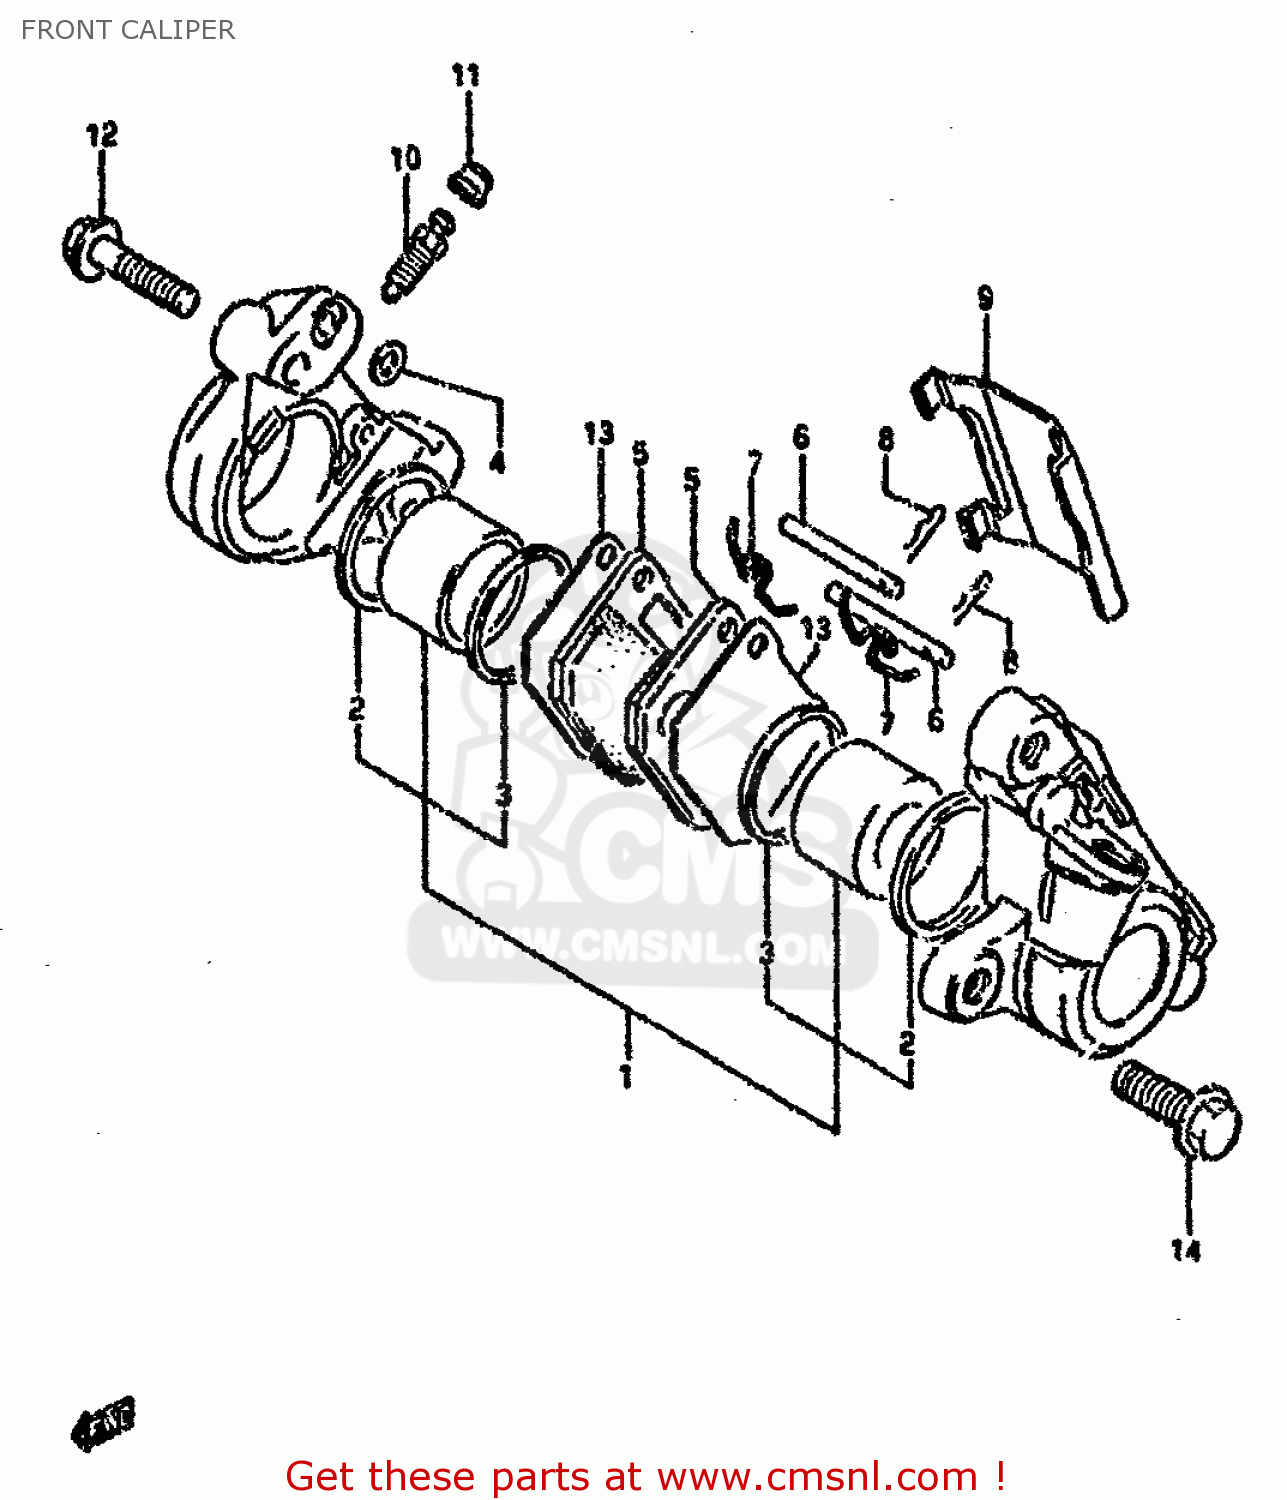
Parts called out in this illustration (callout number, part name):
1	PISTON / SEAL SET
2	SEAL,PISTON
3	SEAL,WIPER
4	SEAL,JOINT
5	PAD (MCA)
6	PIN,PAD
7	SPRING
8	CLIP,PAD PIN
9	COVER
10	BLEEDER
11	CAP,BLEEDER PLUG
12	BOLT
13	SHIM
14	BOLT
